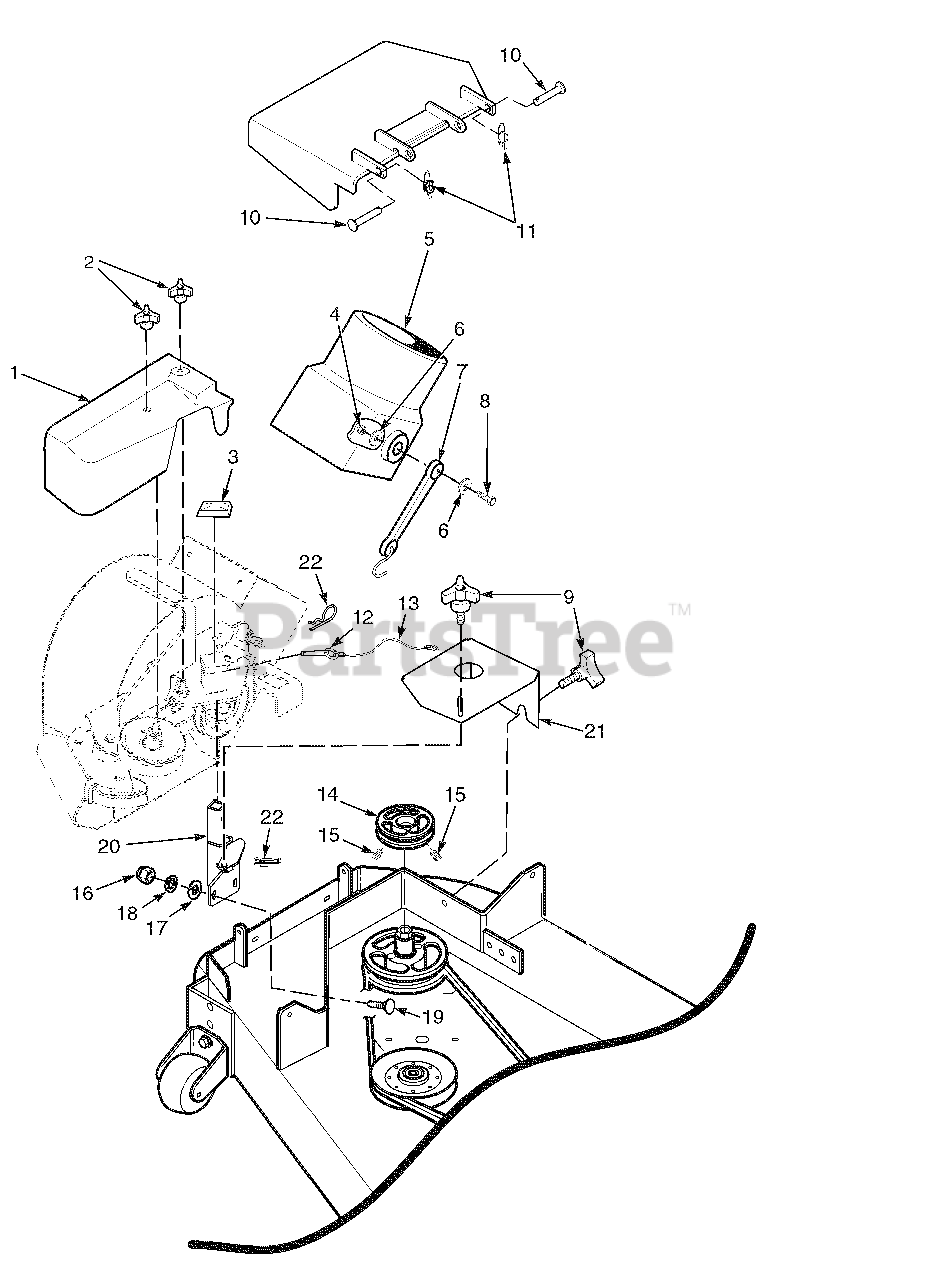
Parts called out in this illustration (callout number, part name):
1	Belt Cover, GC-STWC - 61"
2	Wingnut, Plastic 3/8 Small
3	Cap, Square Vinyl
4	Nut, Elastic Stop 1/4-20
5	Adapter, Blower GC-STT
6	Flatwasher, 1/4-.312 x .750 x .065
7	Rubber Strap 7-3/4"
8	Bolt, Hex Head 1/4-20 x 1-1/4"
9	Knob W/Stud, 3/8-16 x 1-1/4"
10	Clevis Pin, 5/16 x 1-1/2"
11	Pin, Rue Cotter 5/16 Dia.
12	Pin, Ring 1/2 x 2-1/4"
13	Lanyard
14	Pulley, 5-1/2" for 61" Deck
15	Setscrew, 5/16-18 x 3/8"
16	Nut, Elastic Stop 1/2-13
17	Lockwasher, 1/2"
18	Flatwasher, 1/2-.531 x 1.062 x .095
19	Bolt, Hex Head 1/2-13 x 1-1/2" Grade 5
20	Mounting Post Weldment, Blower - 61"
21	Belt Cover, GC-STWC-61
22	Hair Pin Cotter, .177 x 3-1/4"
